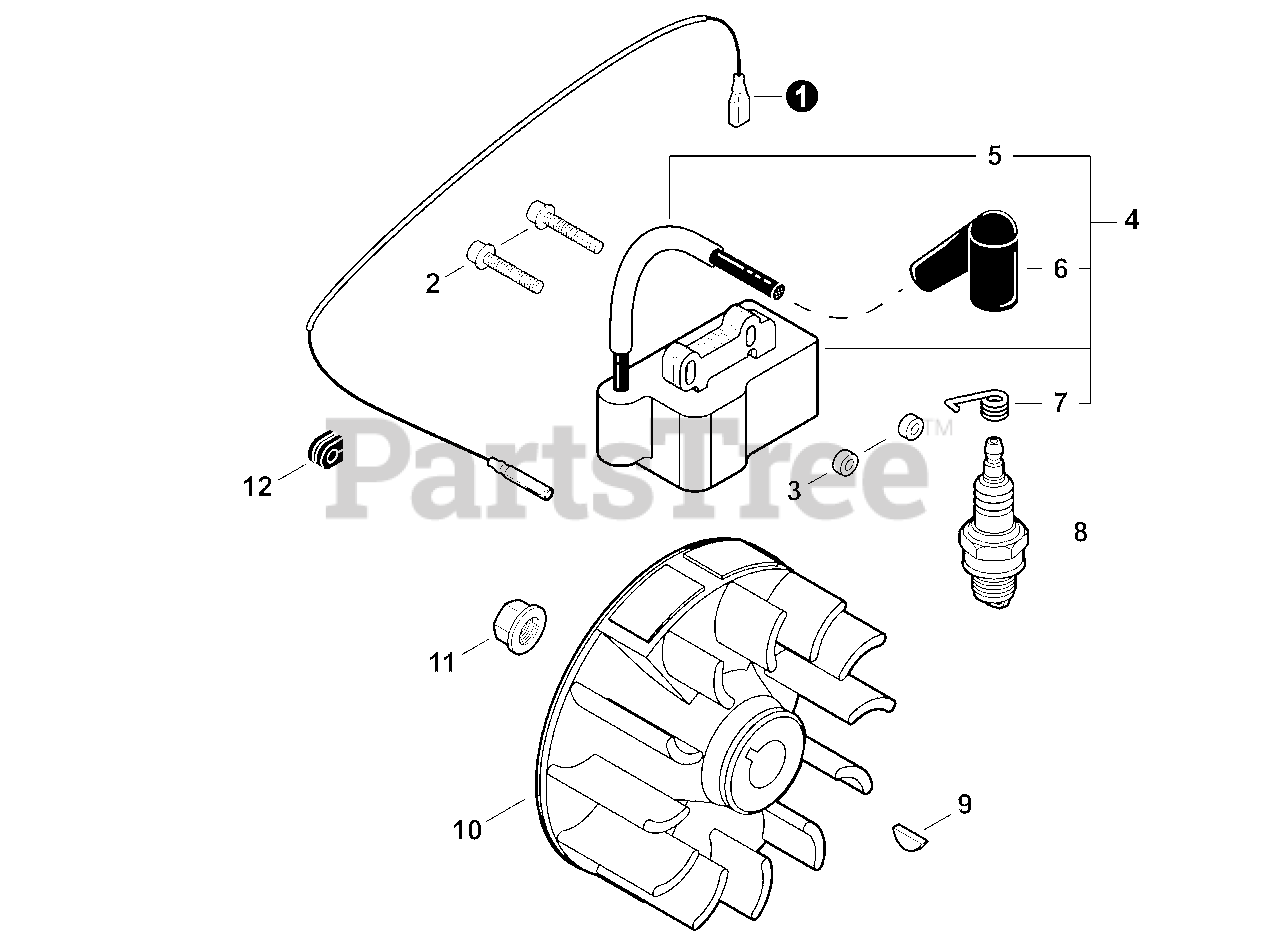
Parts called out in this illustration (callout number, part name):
1	LEAD - IGNITION
2	BOLT M4×26
3	INSULATOR 4.2×11×6
4	COIL ASSY, IGNITION
5	TUBE, INSULATOR
6	CAP, SPARK PLUG
7	TERMINAL, SPARK PLUG
8	SPARK PLUG - CMR5H
9	KEY, WOODRUFF 3×10
10	FLYWHEEL
11	NUT, CRANKSHAFT M8
12	GROMMET, LEAD
